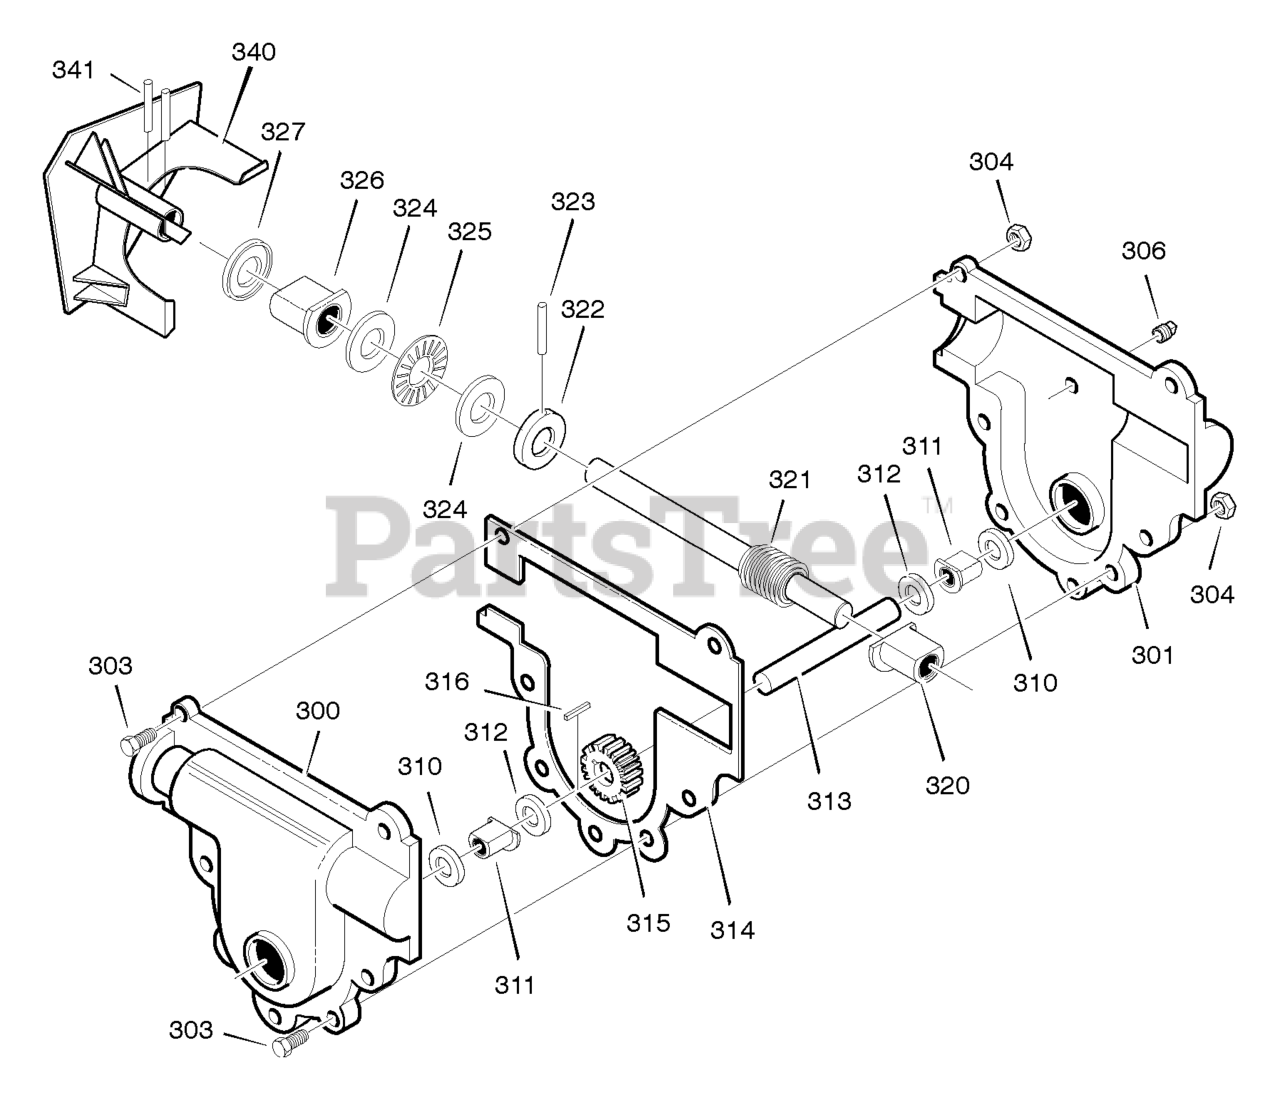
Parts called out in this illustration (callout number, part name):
300	CASE, GEAR, RH
301	CASE, GEAR, LH
306	SCREW
310	SEAL, OIL
311	BEARING, FL
312	WASHER, FLAT
313	SHAFT, OUTPUT
315	GEAR, WORM
316	KEY, WOODRUFF
320	BRNG, FL
321	SHAFT, INPUT
322	COLLAR, THRUST
323	PIN, SPRING
324	WASHER, FLAT
325	BRNG, ROLL
326	BRNG, FL
327	SEAL, OIL
340	IMPELLER ASSEMBLY
341	PIN, SPRING
